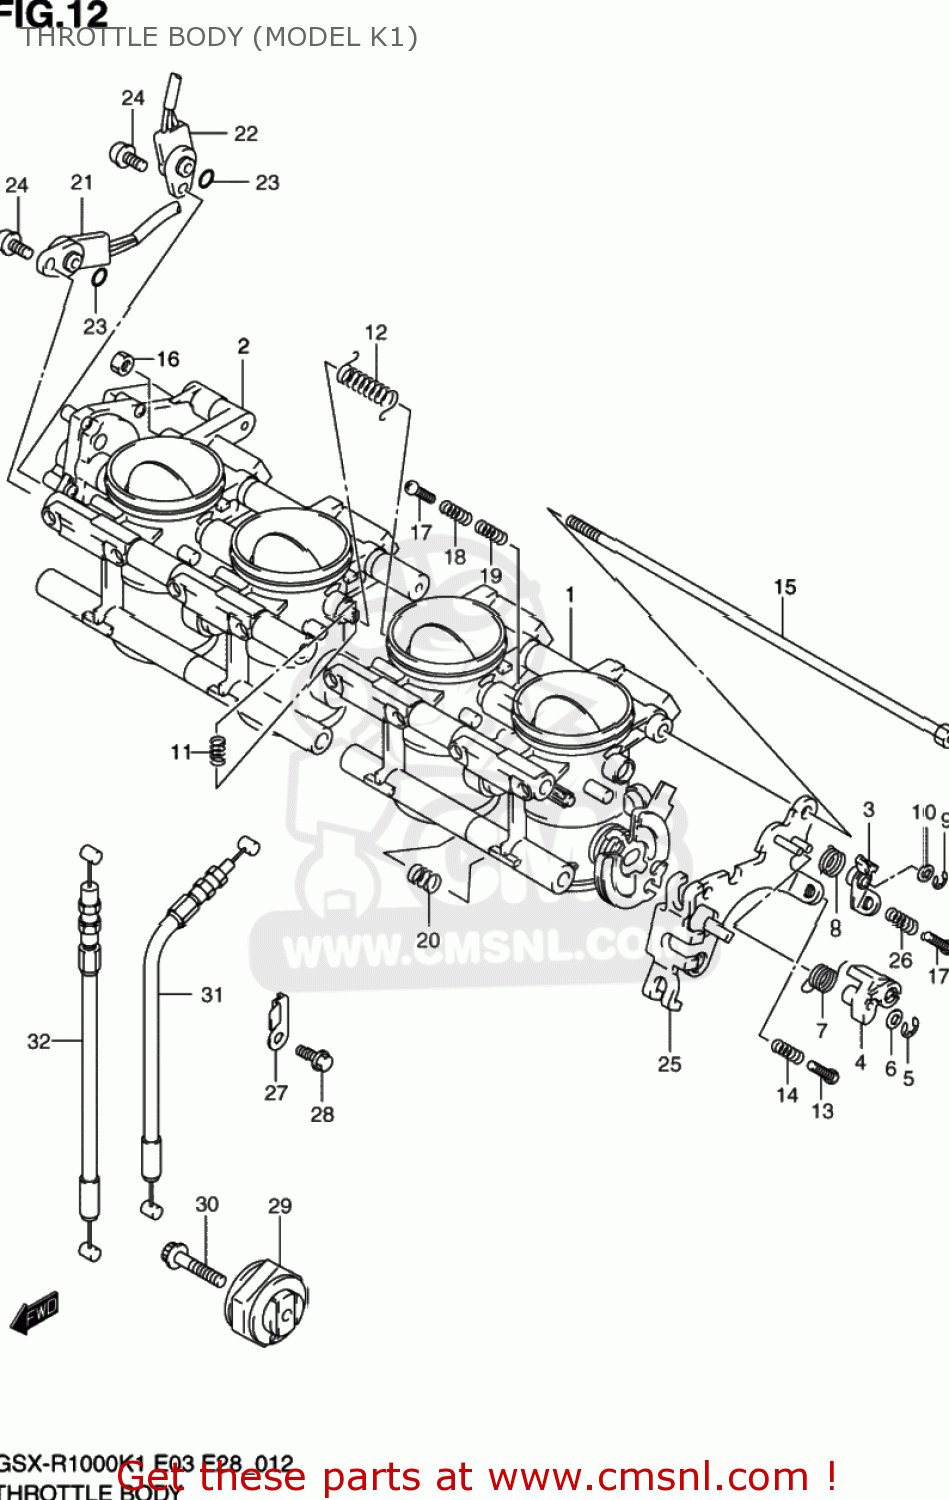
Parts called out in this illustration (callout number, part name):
1	BODY SET,THROT
2	BODY SET,THROTTLE #3/#4
3	LINK,LEVER
4	LEVER,LINK
5	E CLIP
6	WASHER
7	SPRING
8	SPRING
9	E CLIP
10	WASHER
11	SPRING
12	SPRING
13	SCREW,STOP
14	SPRING
15	BOLT
16	NUT
17	SCREW,STOP
18	SPRING
19	SPRING
20	SPRING
21	SENSOR ASSY,TH
22	SENSOR ASSY,TH
23	O RING
24	SCREW
25	PLATE,STAY
26	SPRING
27	BRACKET,EXHAUST VALVE CABLE
28	BOLT
29	PULLEY,CONTROLLER
30	BOLT
31	CABLE,EXHAUST VALVE NO.1
32	CABLE,EXHAUST VALVE NO.2
